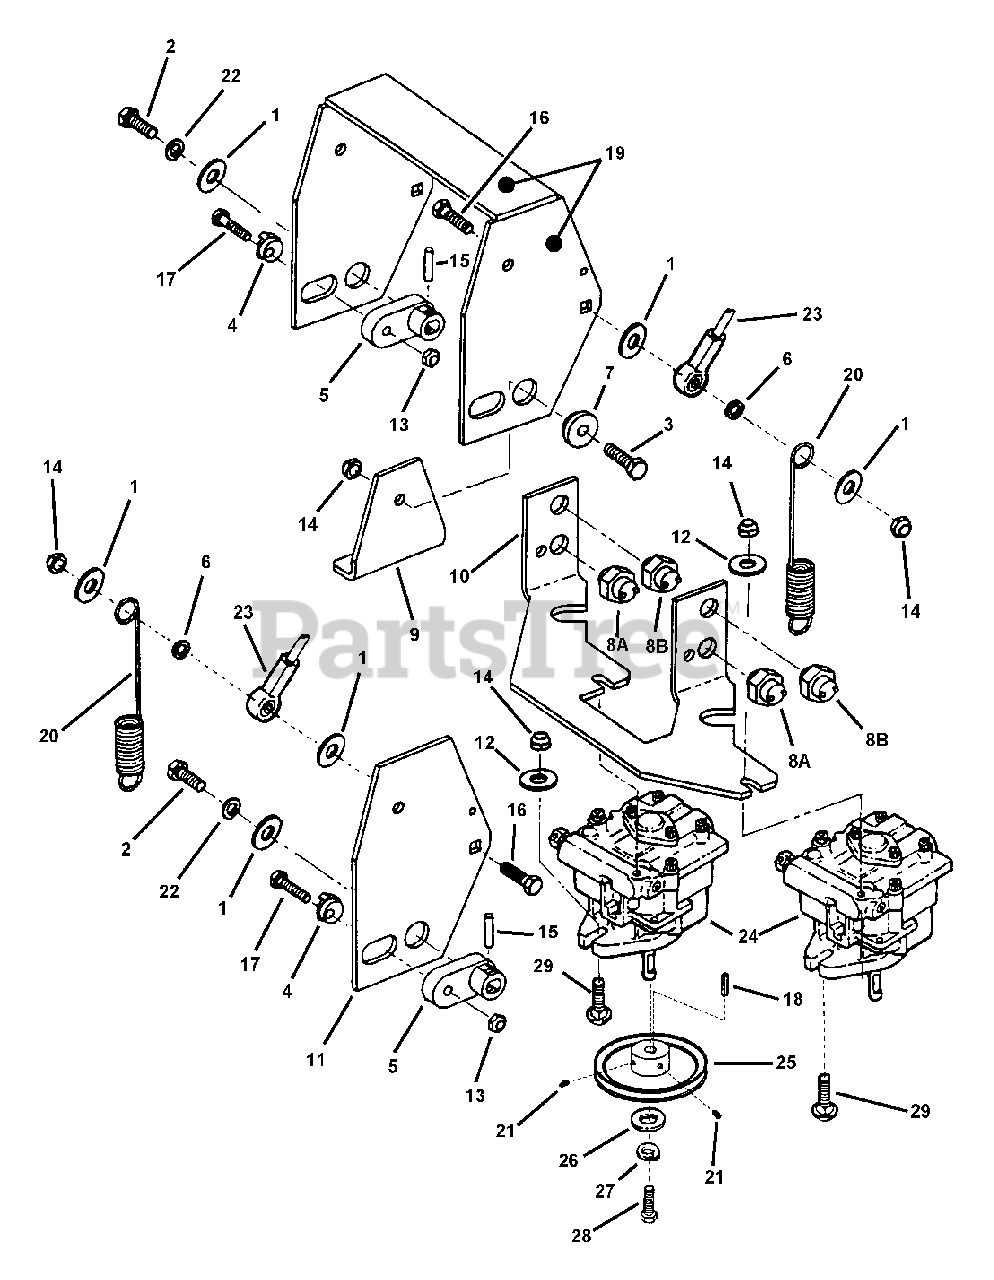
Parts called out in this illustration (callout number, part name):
1	WASHER, 3/8" I.D. x 7/8" O.D. x 1/16" Flat
2	BOLT, 5/16-18 x 1/2" Hex Flange Lock, Grade 5
3	BOLT, 5/16-18 X 2", GD5
4	ECCENTRIC
5	ARM, Pump
6	BUSHING, Spring
7	BUSHING
8A	SWITCH, Transmission NO
8B	SWITCH, Transmission NC
9	BRACKET, Pivot
10	BRACKET, Switch
11	ARM, Shift, Left
12	WASHER, 3/8" Flat
13	NUT, 1/4-20 Hex Top Lock, Grade B
14	NUT, 5/16-18 Hex Top Lock, Grade B
15	PIN, 5mm x 25mm Roll
16	BOLT, 5/16-18 X 1-1/4 GD5 YZ
17	SCREW, 1/4-20 x 1-1/4", Grade 5
18	KEY, 5mm x 25mm
19	CRANK (Weldment)
20	SPRING, Traction Control
21	SET SCREW, 5/16-18 x 3/8" Knurled Cup
22	WASHER, 5/16 Split Lock
24	PUMP, Hydraulic
25	PULLEY, 5-1/2"
26	WASHER, 1/4" I.D. x 1" O.D. x 1/8" Flat
27	WASHER, 1/4" I.D. Split Lock
28	SCREW, M6 1.0X12MM, Hex Head, CZ
29	BOLT, 3/8-16 x 1-1/4" Short Square Neck, Grade 5
